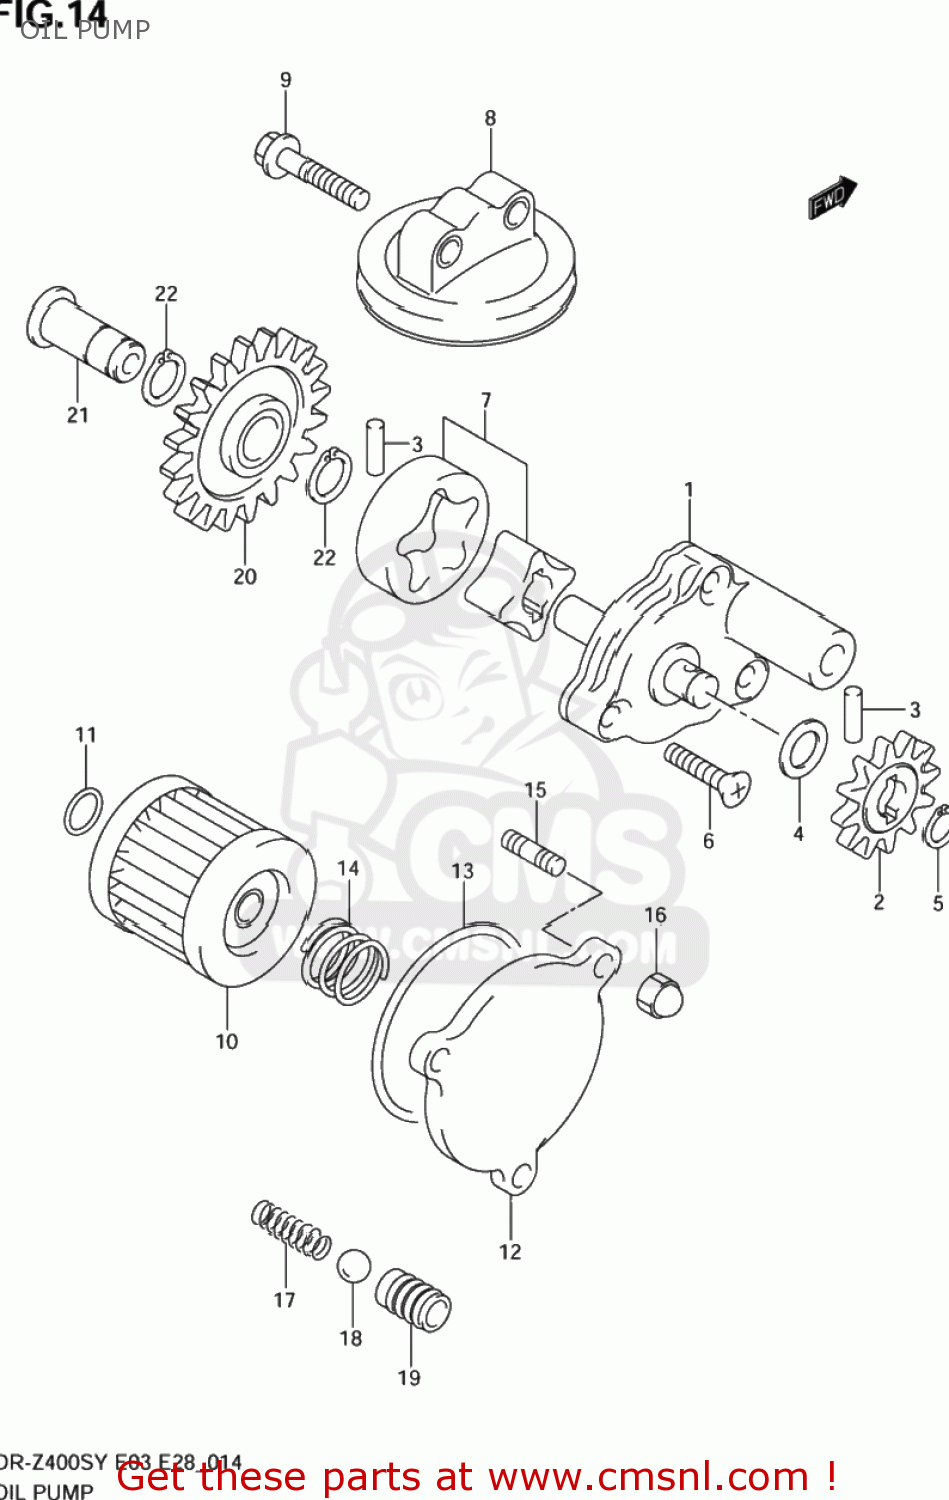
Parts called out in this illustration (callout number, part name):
1	PUMP ASSY,ENGINE OIL NO.1
2	GEAR,OIL PUMP DRIVEN
3	PIN(4X15.8)
4	SHIM(10X18X0.5)
5	CIRCLIP,10MM
6	SCREW
7	ROTOR SET,OIL PUMP,NO.2
8	STRAINER,OIL PUMP NO.2
9	BOLT
10	FILTER ASSY,ENGINE OIL
11	O RING(D:1.9,ID:13)
12	CAP,OIL FILTER
13	O RING(D:2.4,ID:52.6)
14	SPRING
15	BOLT,STUD
16	NUT
17	SPRING
18	BALL
19	SEAT,OIL CHECK VALVE
20	GEAR,OIL PUMP IDLE
21	SHAFT,OIL PUMP IDLE GEAR
22	CIRCLIP,12 MM
